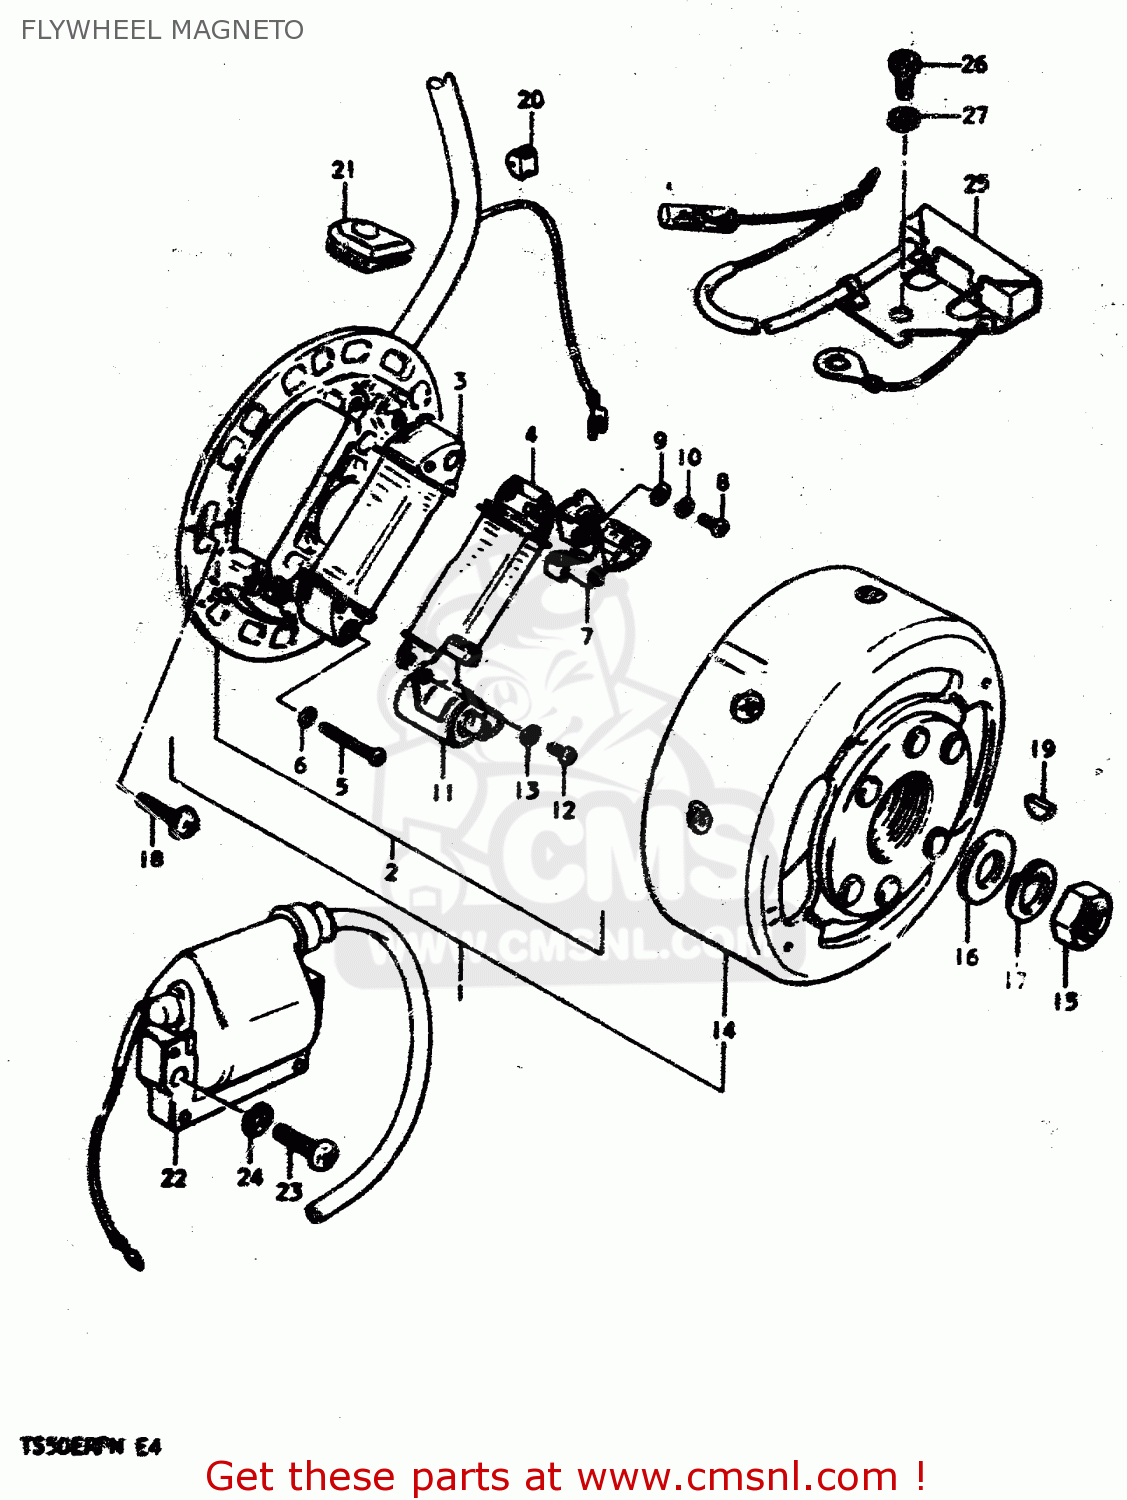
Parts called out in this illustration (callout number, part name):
1	MAGNETO ASSY
2	STATOR ASSY
3	COIL, LIGHTING
4	COIL,PRIMARY
5	SCREW
6	LOCK WASHER
7	POINT ASSY,CONTACT
8	SCREW(4X10)
9	WASHER
10	LOCK WASHER
11	CONDENSER
12	SCREW
13	LOCK WASHER
14	ROTOR ASSY
15	NUT (10MM)
16	WASHER
17	LOCK WASHER
18	SCREW(5X14)
19	KEY
20	GROMMET,NEUTRAL LEAD WIRE
21	GROMMET
22	COIL ASSEMBLY,IGNITION
23	SCREW
24	LOCK WASHER
25	RESISTOR ASSY
26	SCREW
27	LOCK WASHER
